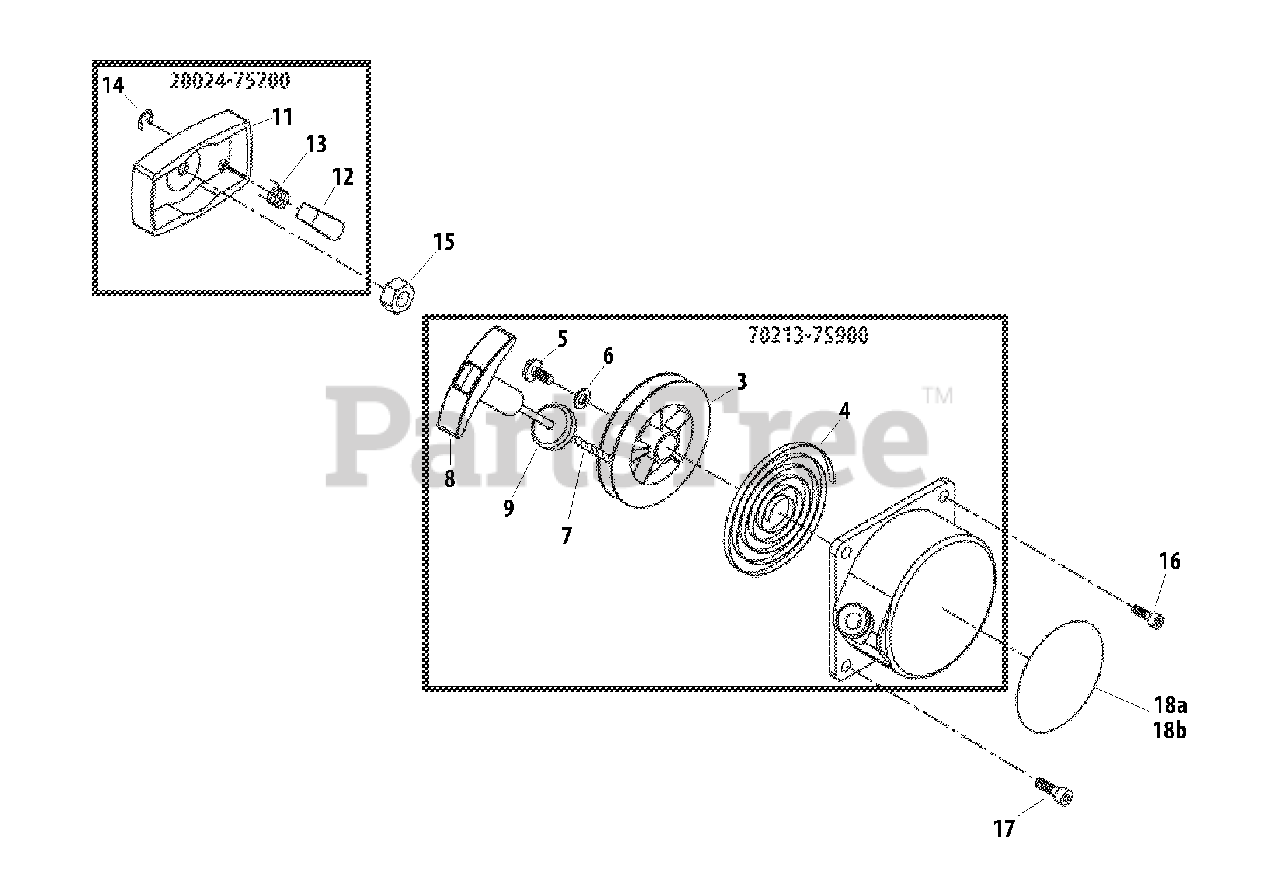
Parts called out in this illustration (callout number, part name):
3	REEL, ROPE
4	SPRING, RECOIL
5	SCREW 5
6	WASHER
7	ROPE, STARTER
8	GRIP, STARTER
9	DAMPER
11	PULLEY, STARTER
12	PAWL, STARTER
13	SPRING, RETURN
14	E-RING 4
15	NUT
16	BOLT M5×20
17	BOLT M5×25
18A	LABEL, TRADE (RED)
18B	LABEL - MODEL
20024-75200	PULLEY ASSY, STARTER
70213-75900	STARTER ASSY, RECOIL
